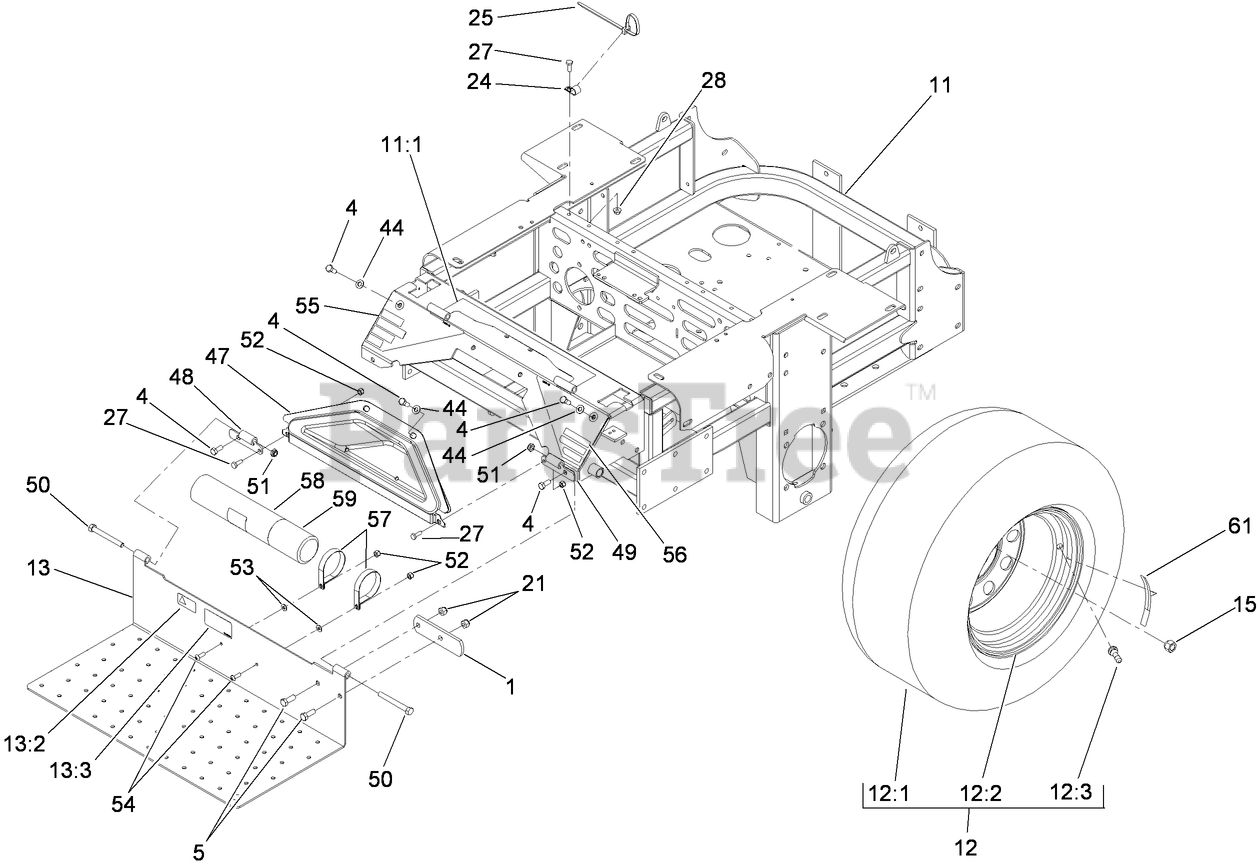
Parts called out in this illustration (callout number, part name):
1	STOP-BRAKE, PARK
4	SCREW-HH
5	SCREW-HH
11	FRAME ASM
11:1	DECAL-CONSOLE, TOP
12	WHEEL AND TIRE ASM
12:3	STEM-VALVE
13	FLOORPAN
13:2	DECAL-PROTECTION, EAR
13:3	Decal-Location, Manual
15	NUT-LUG
21	NUT-LOCK, NI
24	CLIP-LOOM
25	TIE-PLASTIC
27	SCREW-HH
28	NUT-HF
44	WASHER-FLAT
47	Pocket
48	Hinge-Floorpan, LH
49	Hinge-Floorpan, RH
50	SCREW-HH
51	NUT-LOCK, NI
52	NUT-LOCK, NI
53	WASHER-FLAT
54	SCREW-PRH
55	Decal-Warning
56	Decal-Danger
57	R-Clamp
58	TUBE-MANUAL
59	CAP-HOUSING
61	DECAL
